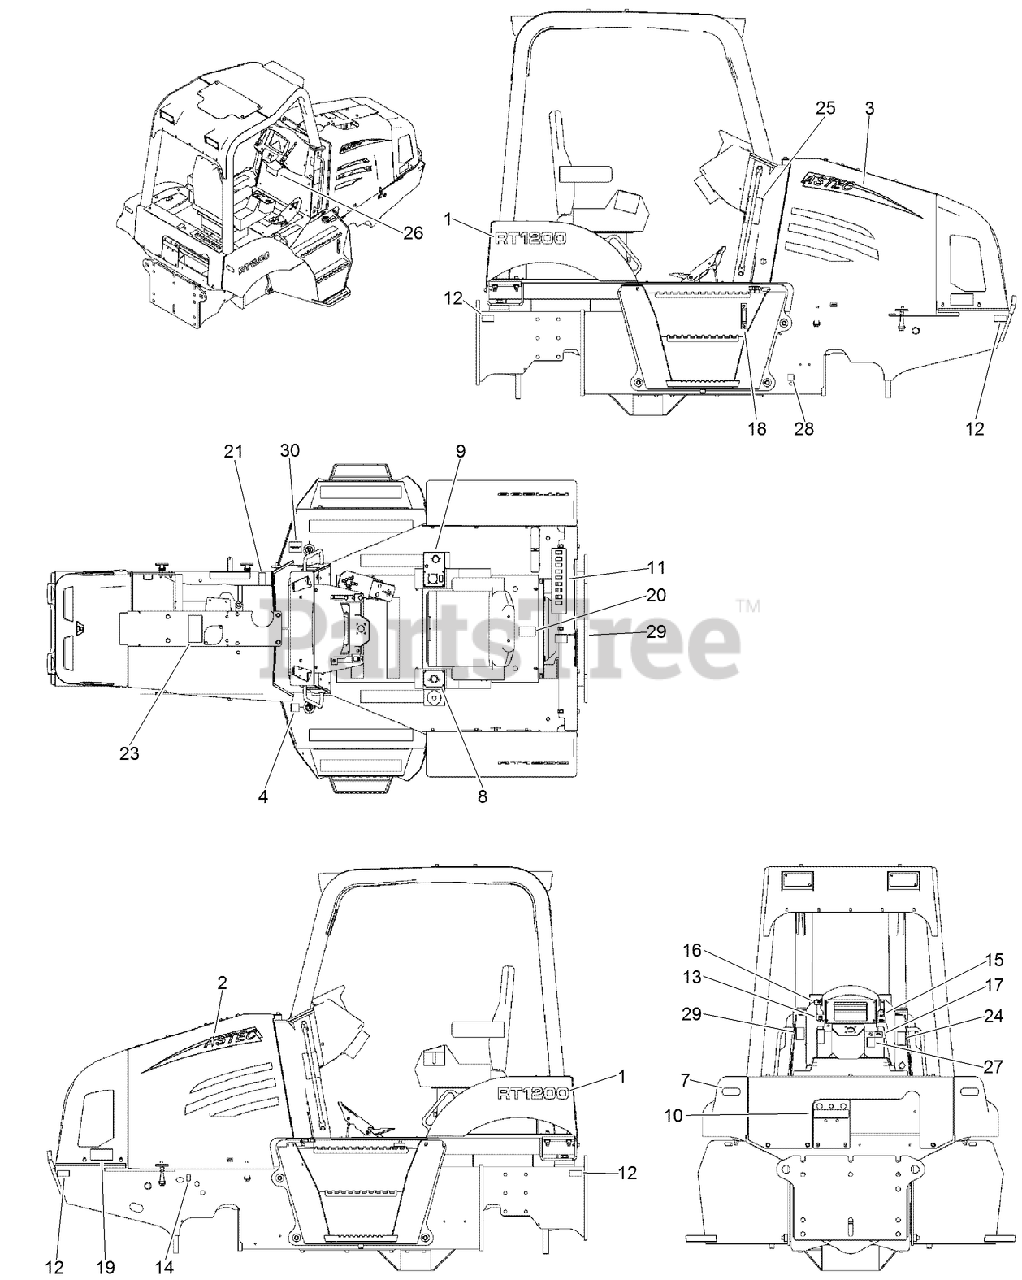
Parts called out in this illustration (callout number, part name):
1	DECAL - RT1200 Model
2	DECAL - Astec Swoosh, Right Hand
3	DECAL - Astec Swoosh, Left Hand
4	DECAL-Diesel Fuel
8	DECAL - Ground Drive Joystick
9	DECAL - Op Rhs Joystick
10	DECAL - Rear Bulkhead ID
11	DECAL - Rear Switches Overlay
12	DECAL-Tie Down / Lift Hook
13	DECAL - Instrument Panel, LH
14	DECAL-Hydraulic Oil, Supply / Return
15	DECAL-Instrument Panel, RH
16	DECAL-Instrument Panel, RH
17	DECAL-Key Switch
18	DECAL-Hydraulic Oil Level
19	DECAL-Fan Entanglement
20	DECAL-Battery Explosion
21	DECAL - Runover Hazard
23	DECAL-Fluid Pressure
24	DECAL-Warning, Hearing Protection Required
25	DECAL-No Riders
26	DECAL-Unexpected Movement
27	DECAL-Read Operators Manual
28	DECAL - Engine Oil Drain
29	DECAL-Warning, Call Before Digging
30	DECAL - Hydraulic Fluid.
